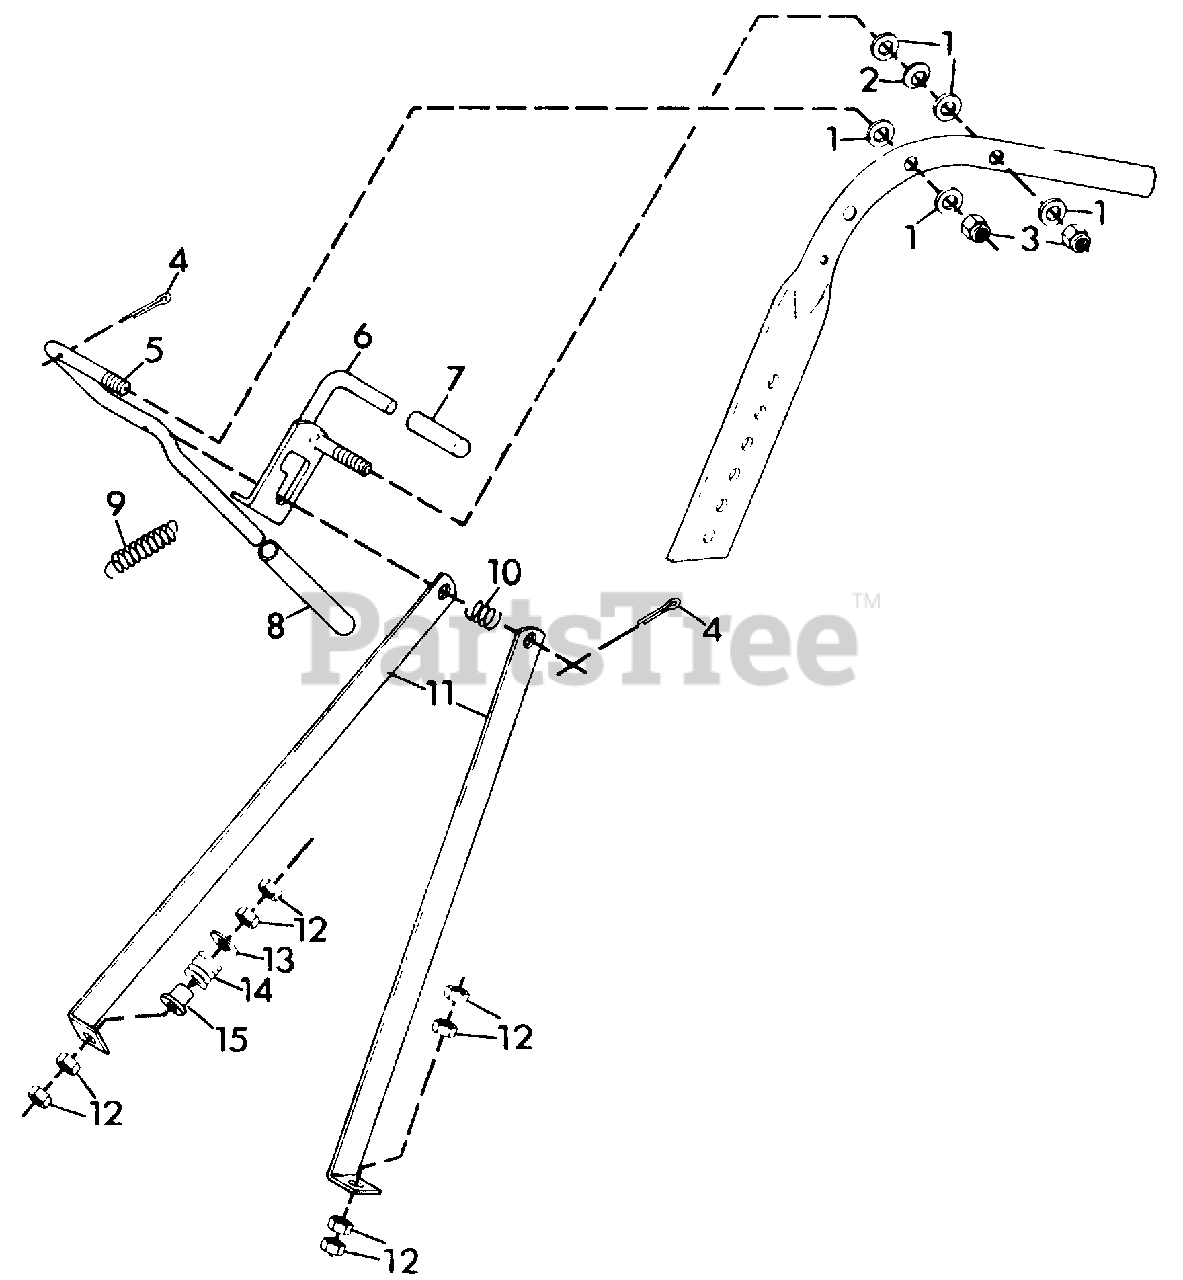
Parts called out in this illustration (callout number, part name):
1	WASHER, NYLON .375X.75X.06
2	WASHER, SPRING .375 I.D.
3	NUT, LOCK 3/8-16
4	PIN, COTTER .09X.75
5	LEVER, STEERING
6	LATCH, STEERING LEVER
7	TIP, BRAKE LOCK LEVER
8	GRIP, HAND CLUTCH LEVER
9	SPRING, EXTENSION
10	SPRING, COMPRESSION
11	STRAP, CLUTCH-BRAKE
12	NUT, HEX 5/16-18
13	WASHER, FLAT .344X.688X.065
14	SPRING, COMP. 1X.78X338
15	BUSHING, INTERLOCK LEVER
